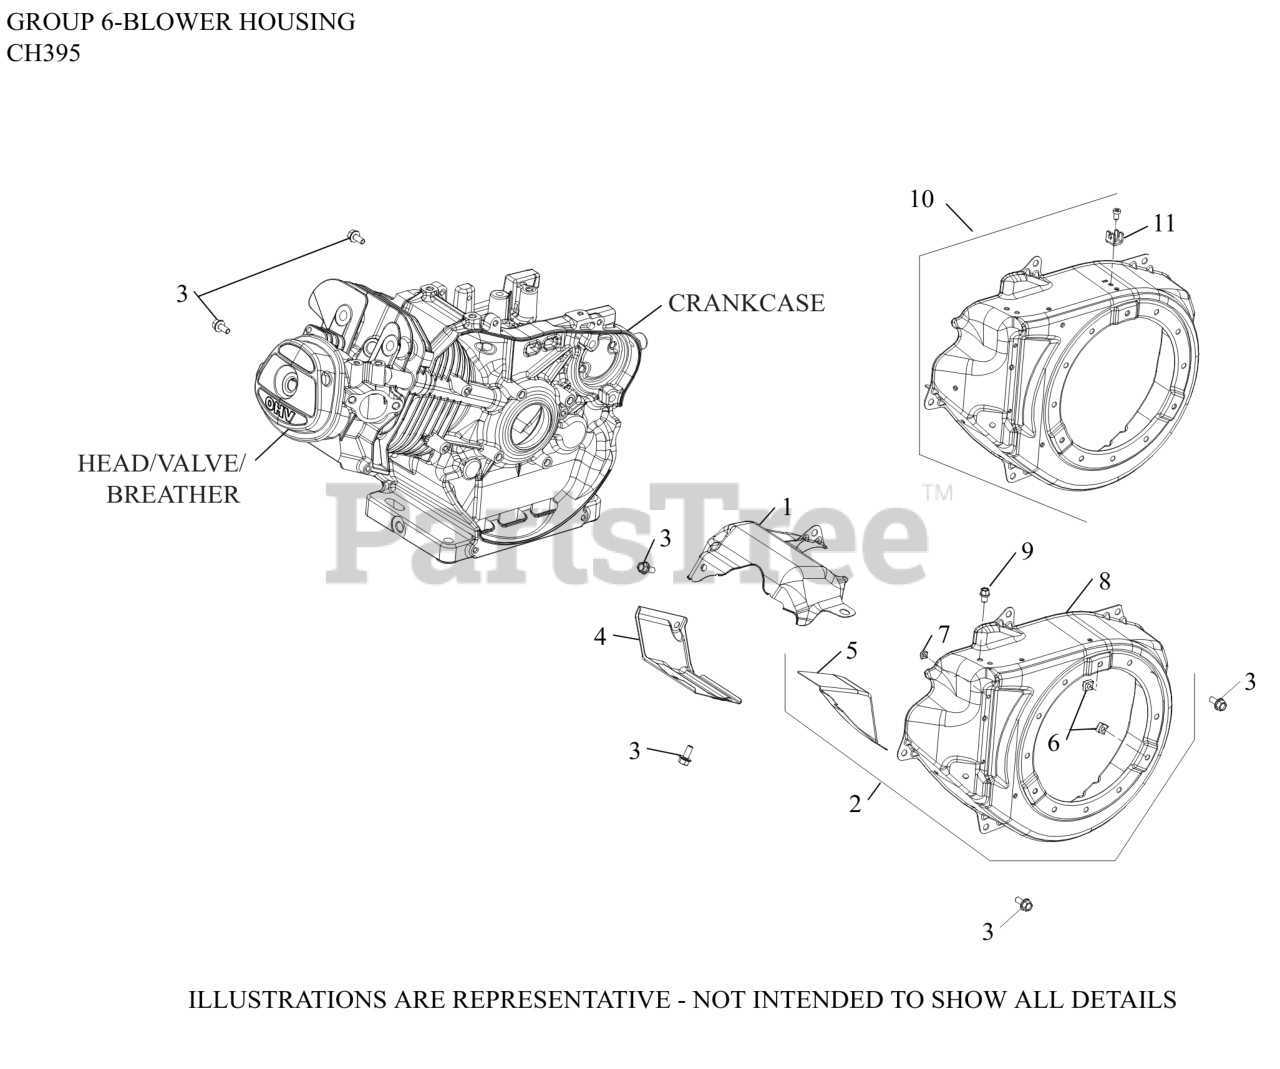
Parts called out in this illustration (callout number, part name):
1	SHIELD, UPPER HEAT
2	KIT, BLOWER HOUSING
3	SCREW, HEX FLANGE (M6)-USE 25 086 433-S
4	SHIELD, CYLINDER HEAD
5	SHIELD, OUTSIDE CYLINDER HEAD
